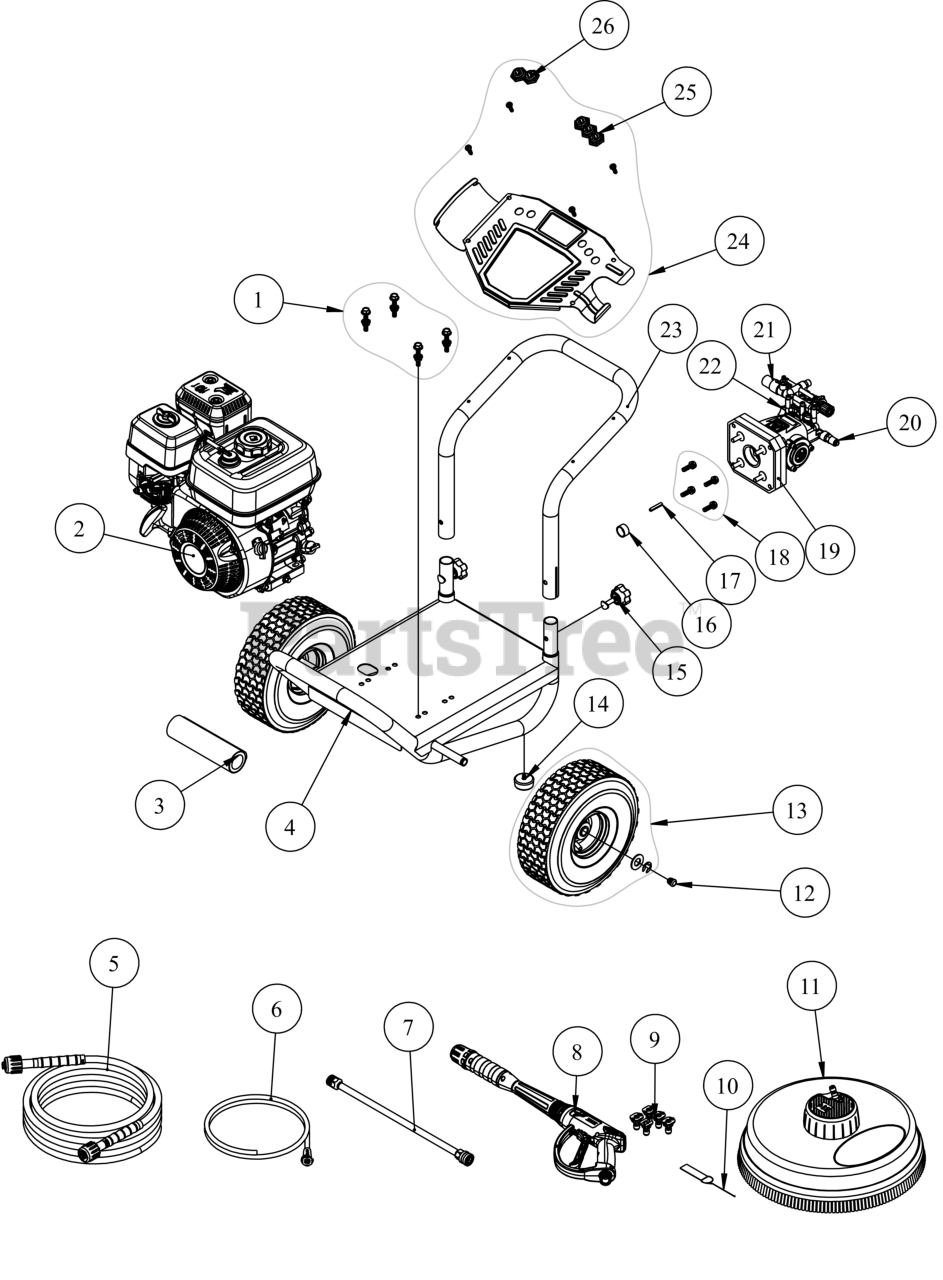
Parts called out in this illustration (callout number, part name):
1	MOUNTING KIT: ENGINE
2	ENGINE, GB210 208CC 50 STATE BLK HORIZ
3	GRIP-HANDLE
4	FRAME, BASE WELDMENT
5	MORFLEX HOSE (5/16 x 25')
6	HOSE-SOAP W/FILTER
7	WAND-SPRAY GUN 16"
8	SPRAY GUN (3600PSI M22)
9	5 PIECE NOZZLE SET
10	TOOL-NOZZLE CLEANING
11	15" SURFACE SCRUBBER
12	CAP, PLASTIC, 5/8 HOLLOW AXLE
13	10" WHEEL (BEIGE)
15	KNOB-HANDLE MTG
16	SPACER, 3/4" ENGINE SHAFT
17	SHAFT KEY (3/16x3/16x1.25)
18	HARDWARE KIT: PUMP MOUNTING
19	AX300 PUMP
20	VALVE-THERMAL RELIEF
21	CONNECTOR-OUTLET PRESR WASH
22	INLET KIT-WATER PRESR WASH
23	HANDLE, CUB YELLOW
24	DASHBOARD SVC ASSY
25	HOLDER-NOZZLE 3 PC
26	HOLDER-NOZZLE 2 PC
